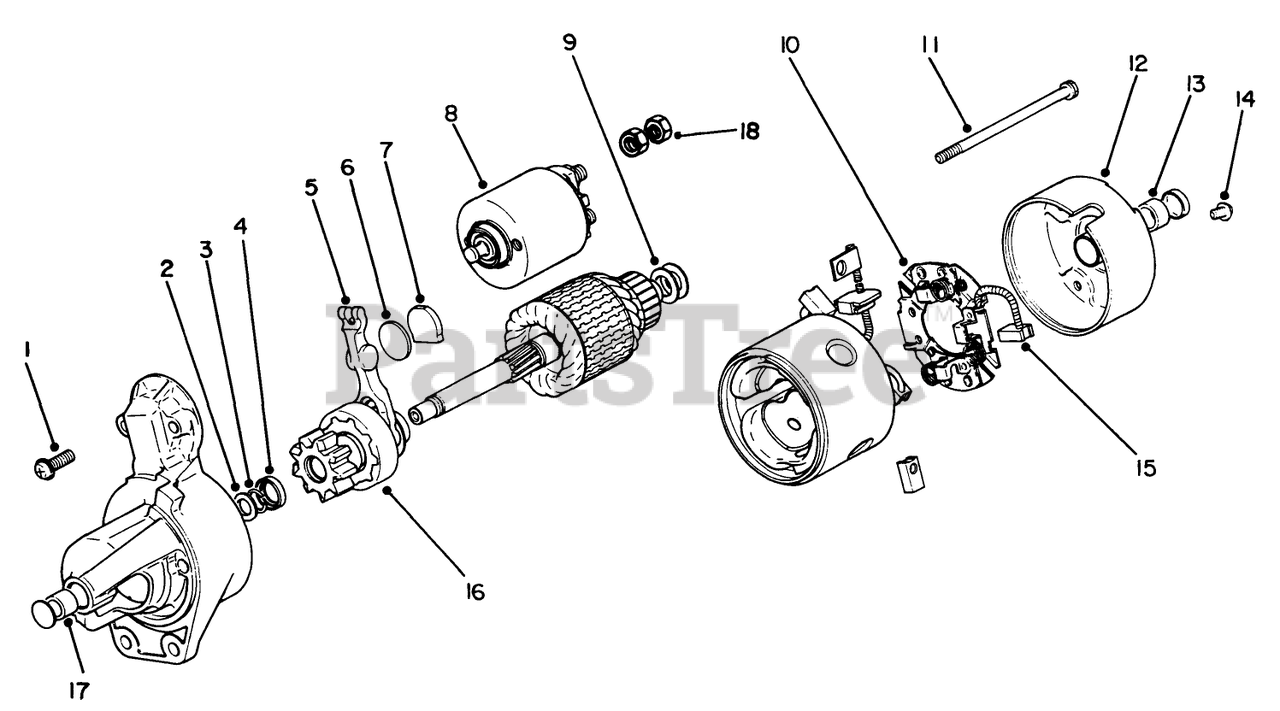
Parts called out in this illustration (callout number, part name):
1	Screw-Solenoid
2	Washer
3	Ring-Pinion Retainer
4	Collar-Pinion Stop
5	Lever-Shift
6	Plate-Wear
7	Plug-Rubber
8	Starter Solenoid Kit
9	Shim-Armature
10	Brush Mounting Kit
11	Bolt
12	Cap Assembly
14	Screw-Brush Holder
15	Brush-Positive
16	Starter Clutch Assembly
18	NUT-JAM
